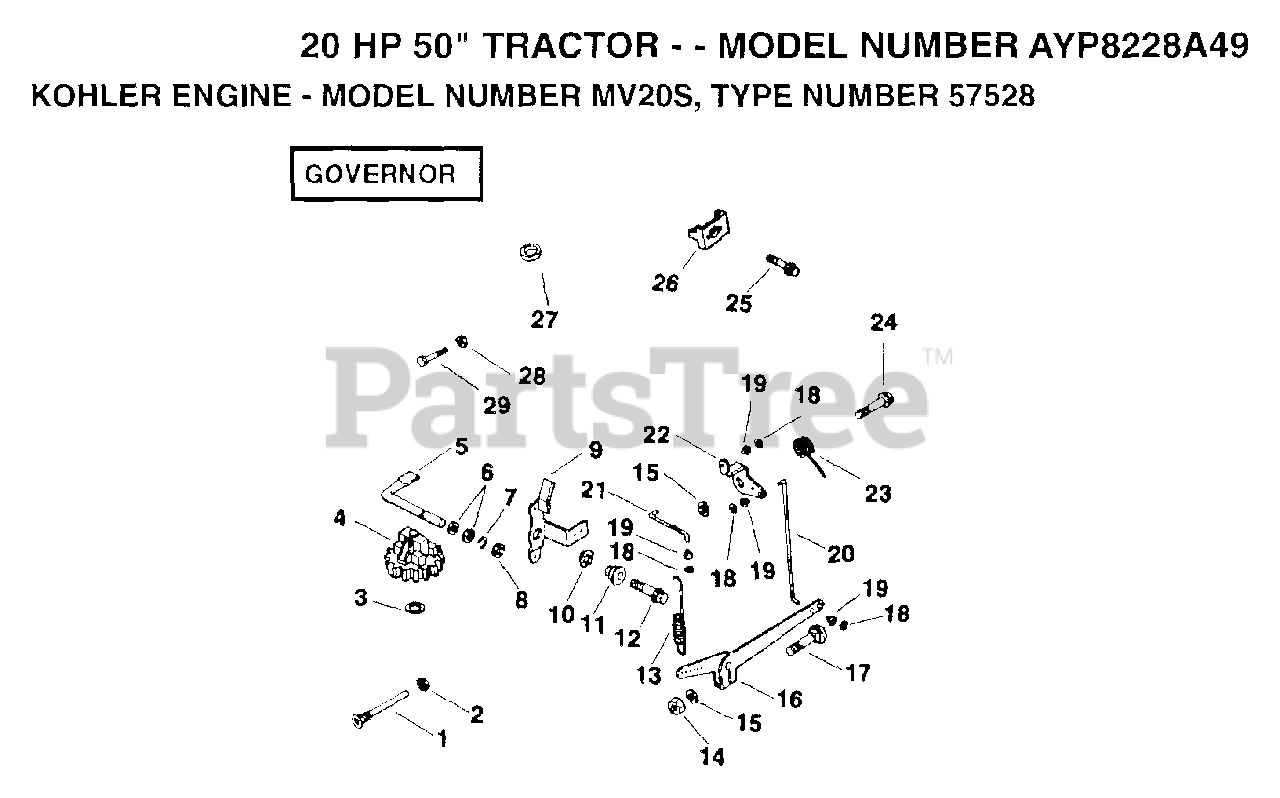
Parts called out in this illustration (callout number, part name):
1	PIN
2	WASHER
3	WASHER
6	WASHER
7	RETAINER
8	WASHER
10	WASHER
12	SCREW, 1/4-20 X 1
14	NUT
15	WASHER, PLAIN 1/4
24	SCREW, HEX 1/4-20 X 5/8
25	SCREW
26	CLAMP
28	NUT, HEX #10-32
